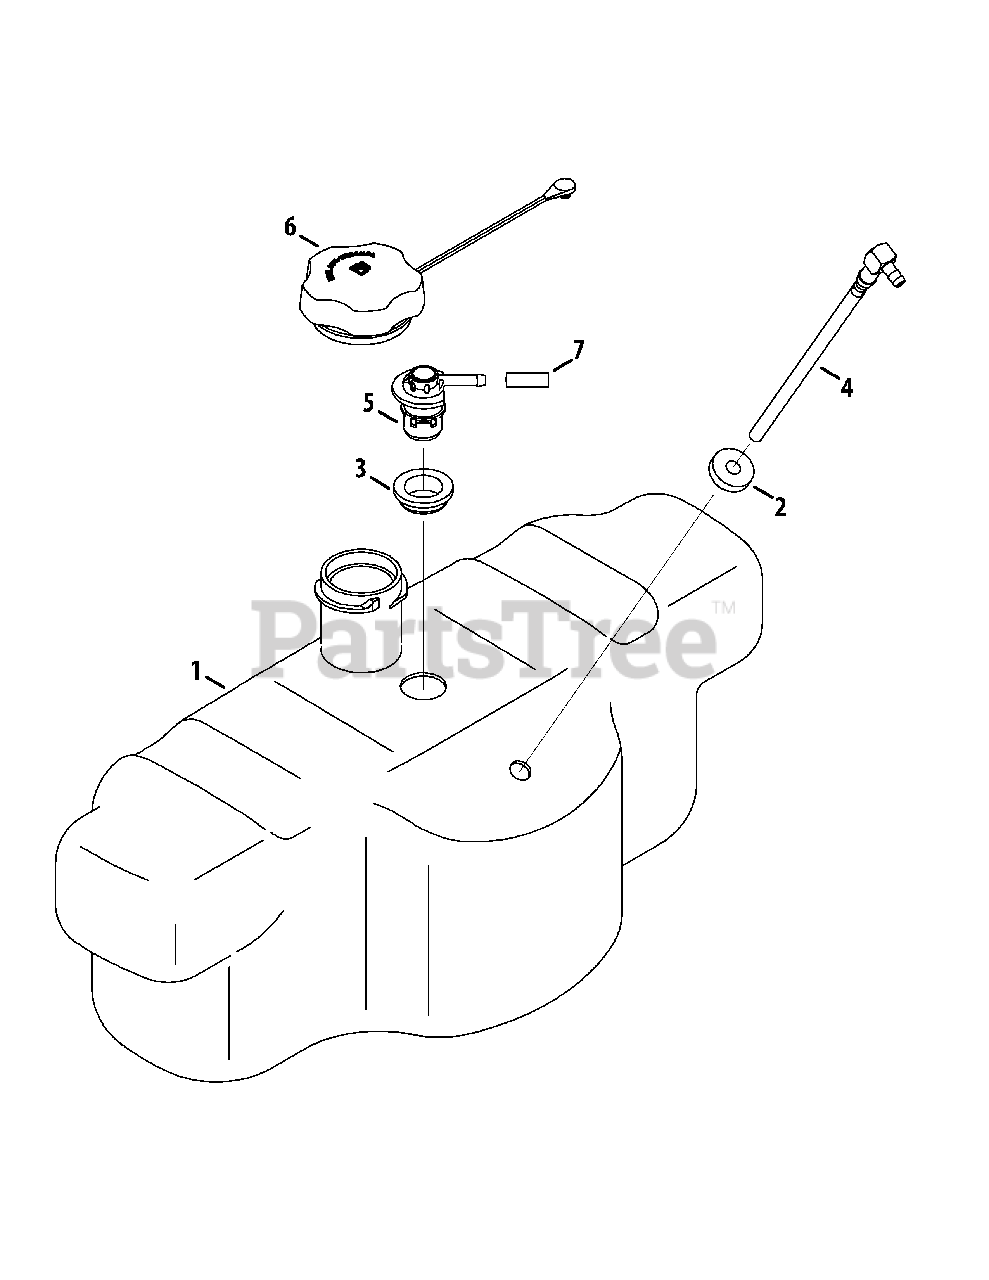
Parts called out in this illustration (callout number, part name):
1	Fuel Tank
2	Fuel Tank Bushing
3	Rubber Grommet
4	Fuel Pickup Fitting
5	Rollover Valve
6	Fuel Cap
7	Vent Hose
